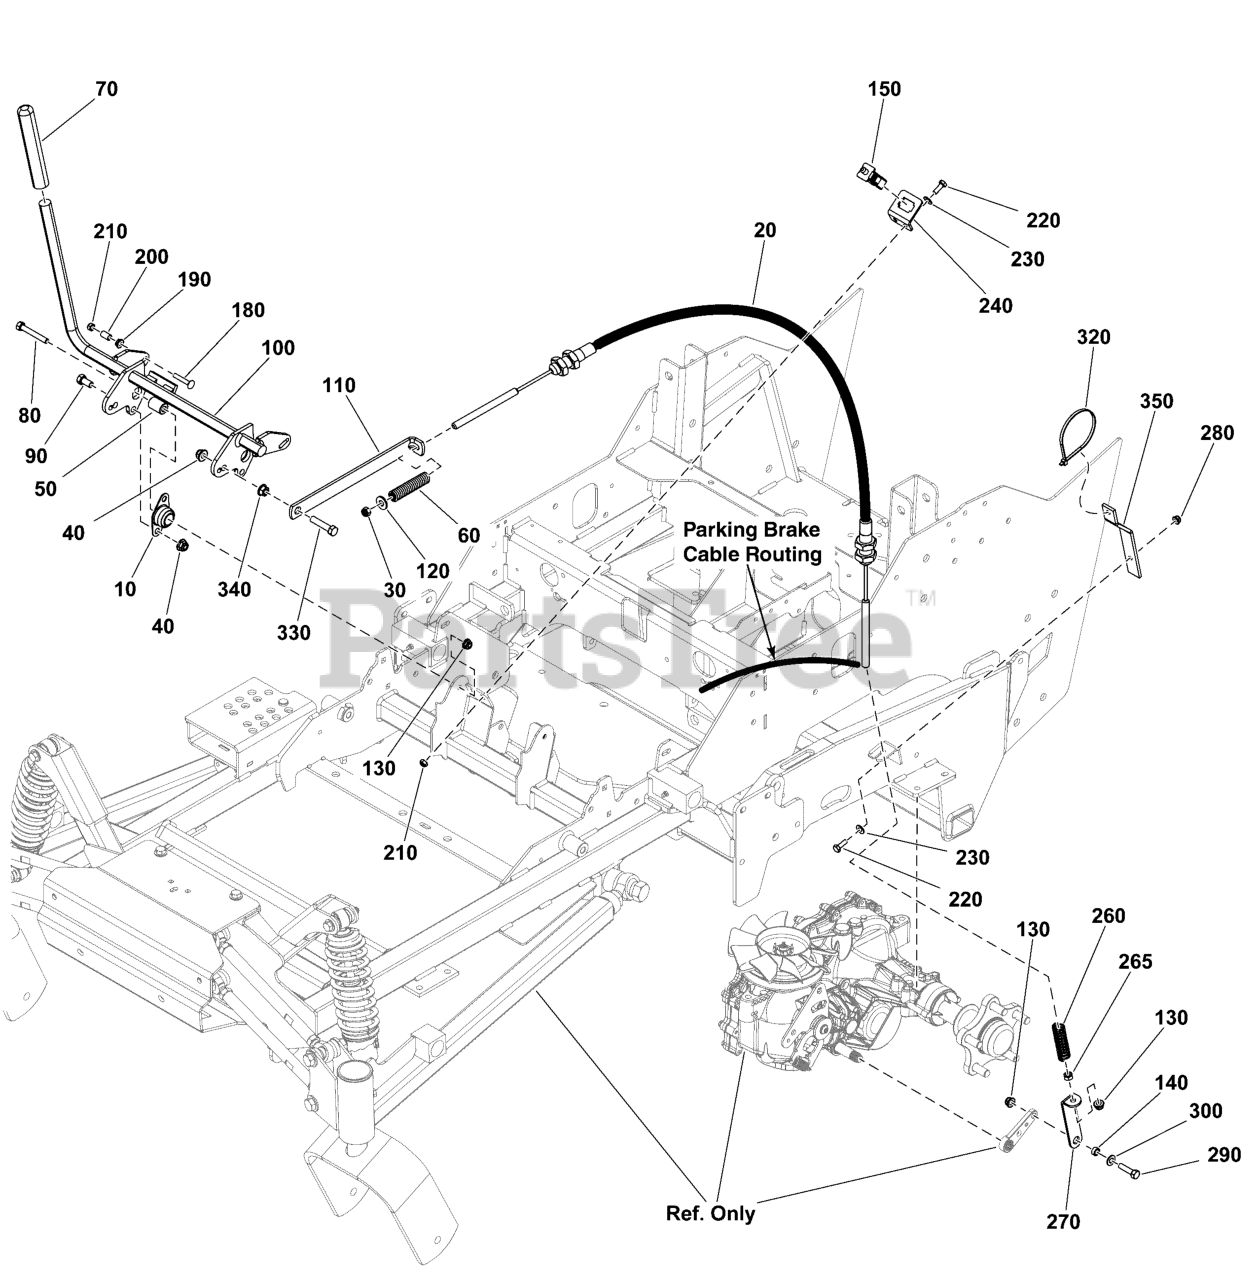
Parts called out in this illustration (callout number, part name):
10	BEARING, BRONZE FLANG
20	CABLE,PARKING BRAKE
30	NUT, 5/16-24 HEX NYLO
40	NUT, 3/8-16 HEX NYLOCK
50	SPACER, .32 X .75 X 1
60	SPRING, CONTROL ROD
70	GRIP, FOAM
80	BOLT, 5/16-18 X 1-3/4
90	BOLT, 3/8-16 X 3/4" G
100	LINK, Lockout
110	LATCH, Parking Brake
130	NUT
140	SPACER, .33 X .50X.25
150	SWITCH, DP NO/NC SNAP
180	BOLT, 1/4-20 X 1.5
210	NUT, 1/4-20 HEX NYLON
220	BOLT, 1/4-20 X 3/4" G
230	WASHER
260	SPRING, COMPRESSION,
265	NUT, 5/16-18 HEX
270	LINK, LOWER BRAKE
300	WASHER
320	TIE WRAP, 11" Long
330	BOLT, 3/8-16 X 1-3/4"
340	NUT, 3/8-16 HEX SERRA
350	BRACKET
